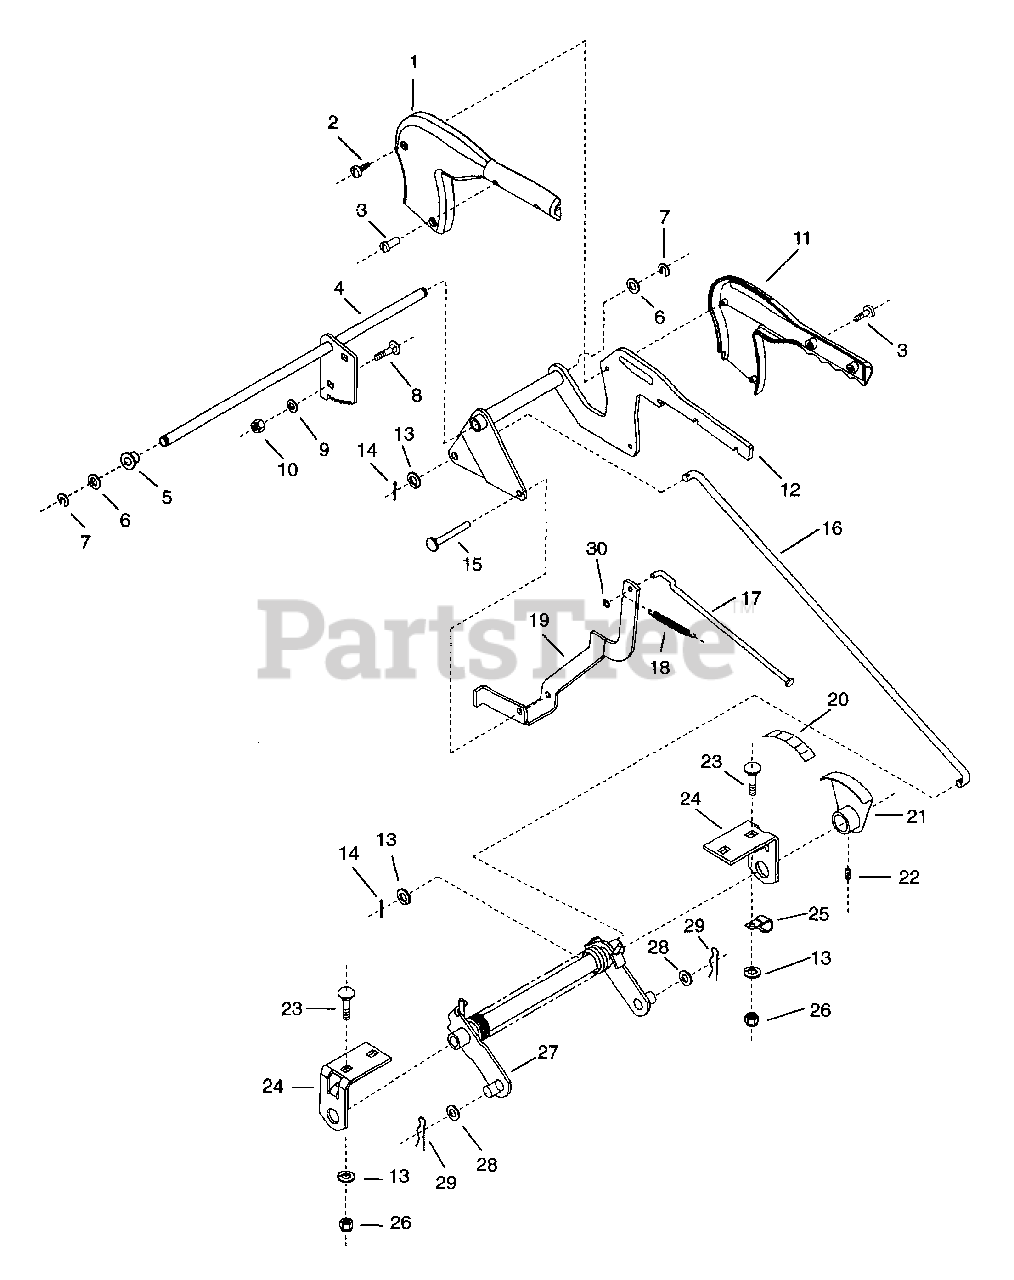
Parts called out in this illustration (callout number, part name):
1	COVER - LIFT RH
2	SCR-TAP 10-16X1.125HI-LOTPHBL
3	POST & SCREW-RAPID ASSY .375
4	PIVOT - LIFT LEVER
5	BSHG-FLG .508X.873X.375X1.19
6	WSHR-FL-STL .520X.827X.062 YZ
7	RG-RTNG-EXT .500X.460
8	BLT-RDHDSQNK .31-18X.75
9	WSHR-FL-STL .323X.625X.062 PL
10	NUT-LK-NYL.312-18 PL
11	COVER - LIFT LH
12	LEVER - LIFT
13	WSHR-FL-STL.406X.812X.065PL
14	PIN-COTR .12X1.0 PL
15	PIN, PIVOT .312 X 2.56
16	LIFT LINK
17	PIN - LIFT
18	SG-TENS .048X.44X2.25 WLD 9
19	LEVER - DETENT
20	DECAL - INDICATOR
21	INDICATOR - DECK HEIGHT
22	SCR-SET .25-20X.25 SKHCUP OH
23	BLT-RDHDSQNK .38-16X.75 SHT PL
24	BRACKET - CENTER LIFT
25	J-CLAMP
26	NUT-LK-CTR .375-16 GR A PL
27	LEVER - CENTER LIFT
28	WSHR-FL-STL .630X1.005X.062 PL
29	PIN-HAIR EXT .12X.31X2.37 PL
30	RG-RTNG-EXT .250X.010
